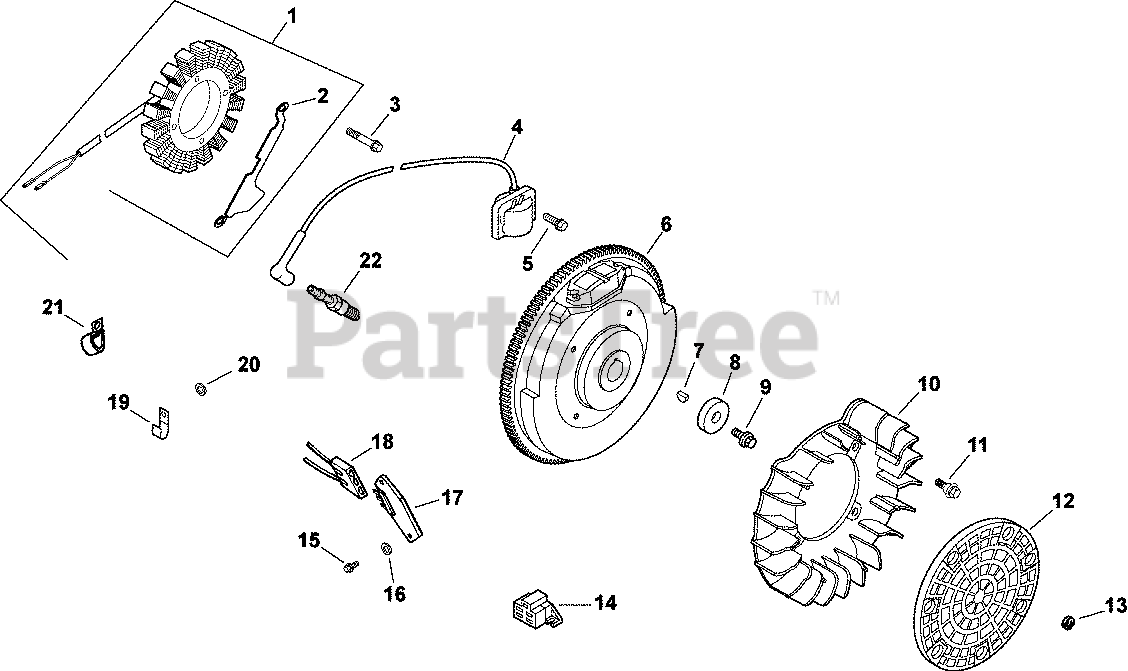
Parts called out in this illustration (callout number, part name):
1	STATOR KIT - USE 237878-S
2	BRACKET, STATOR WIRE
3	SCREW, M5X0.8X25 - (#25086402S)
4	MODULE, IGNITION-USE 24 584 45-S
5	SCREW, FLG THD FRM M5X.8X20-(#25086399S)
6	FLYWHEEL, PAINTED-USE 24 025 55-S
7	KEY, 3/16" X 5/8"
8	WASHER, FLAT 13/32"
9	SCREW, FLG M10X1.5X45 - (#25086361S)
10	FAN (KM)-USE 24 157 15-S
11	BOLT, SHOULDER
12	SCREEN, GRASS
14	CONNECTOR
15	SCREW, PHL HD #11-16X7/8"
16	WASHER, FLAT 3/16"
17	REG/RECT-15 AMP (KM)-USE 41 403 10-S
18	CONNECTOR, BODY (KM)-USE 25 155 41-S
19	CLIP, CABLE
20	WASHER, FLAT 1/4" (O.D. 1/2")
21	CLIP, TUBE & WIRING (KM)
22	PLUG, SPARK (STD)
